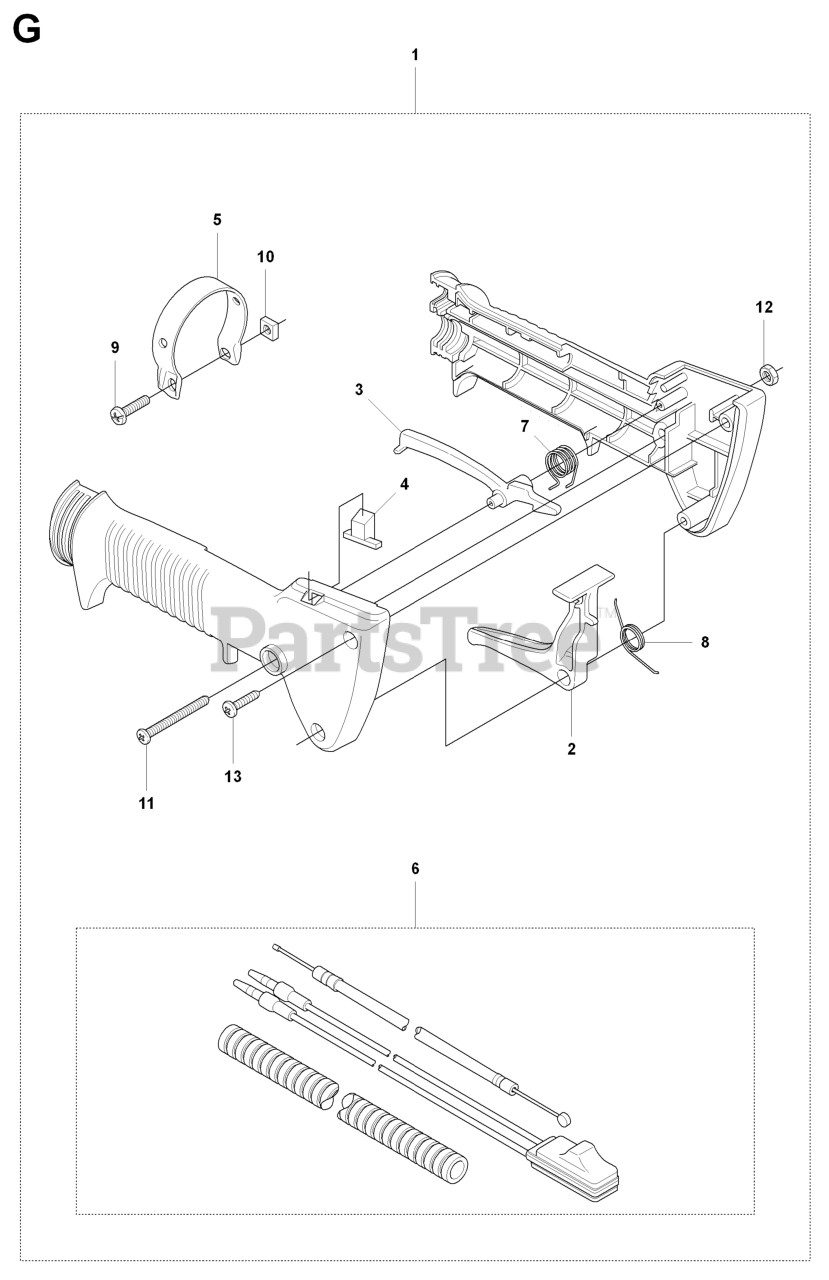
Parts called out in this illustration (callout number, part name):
1	LEVER ASSY
5	CLAMP
6	CABLE COMP
9	SCREW
10	NUT
